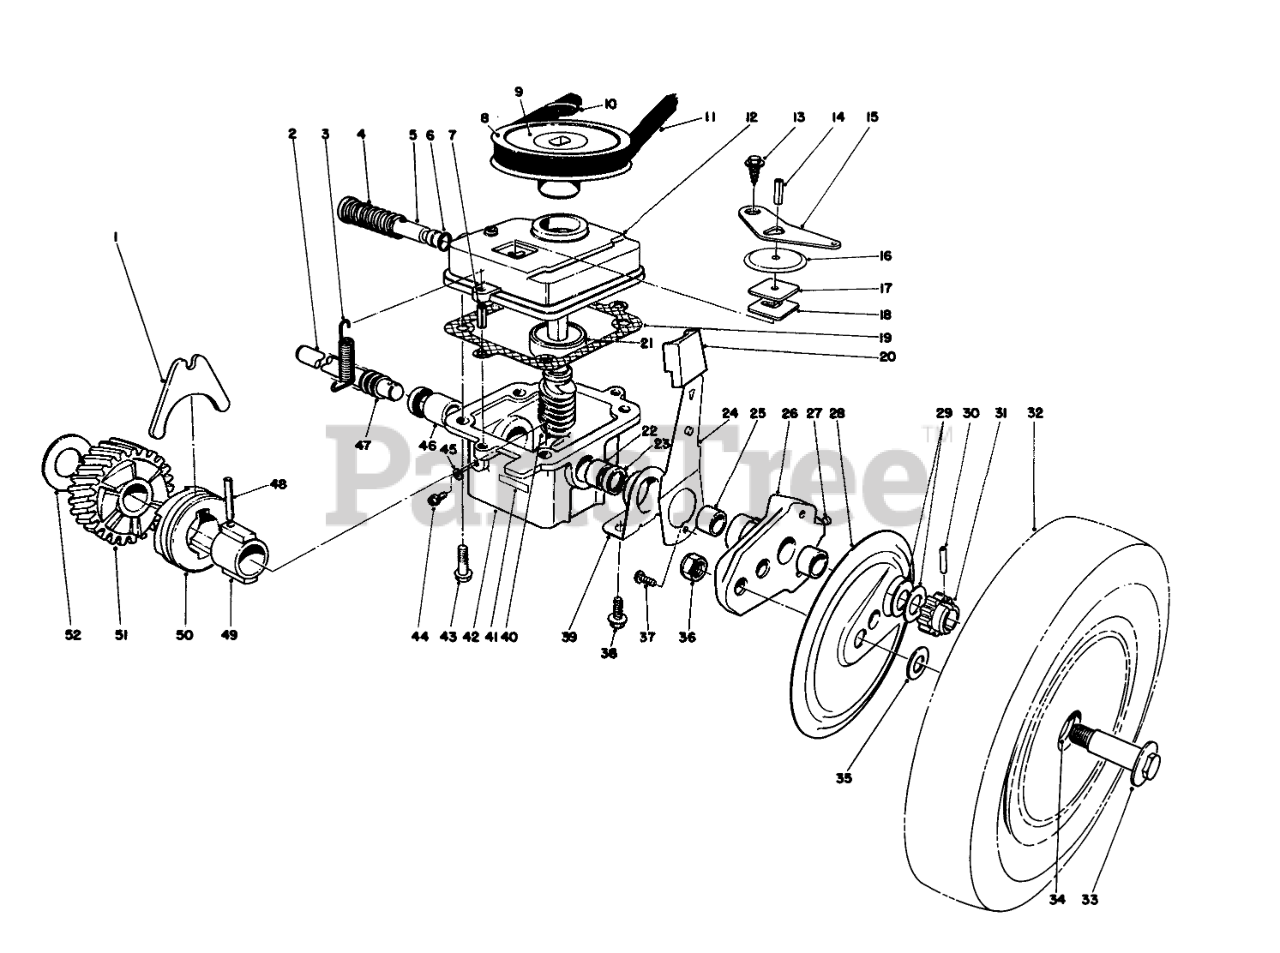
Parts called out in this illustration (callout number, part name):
1	SHIFTER FORK
2	DRIVE SHAFT
3	Spring-Tension
4	SPRING
5	SHIFTER ROD
6	O-RING
7	3/16 X 1/2 ROLL PIN
8	PULLEY
9	DECAL
10	PUSH-ON 93-3236
11	V BELT
12	GEAR CASE COVER
13	Screw
14	SPIROL PIN H D
15	SHIFTER ARM
16	DUST COVER
17	DUST FILTER
18	LATCH PLATE
19	GASKET
20	KNOB-ARM
21	BEARING
22	BUSHING
23	SEAL-OIL
24	SPRING ARM ASSY-FRONT
25	BUSHING
26	Arm-Pivot (Incl. Ref. #25 & 27)
27	FITTING-GREASE
28	WHEEL COVER
29	THRUST WASHER
30	Pin
31	PINION GEAR 15T
32	Wheel, Tire & Gear Assy (Incl. Ref. #34)
33	BOLT-WHEEL
34	BUSHING
35	WASHER
36	Nut
37	SCREW
38	SCREW-HWHTF
39	END CAP
40	Worm Shaft & Gear (Incl. Ref. #51)
41	DECAL
42	Gear Case (Incl. Ref. #22, 23 & 46)
43	Screw
44	NYLON SCREW
45	FILL PLUG GASKET
46	BUSHING
47	COVER-SHAFT, DRIVE
48	COIL PIN
49	SLEEVE
50	CLUTCH JAW
51	Gear-Helical
52	THRUST WASHER
